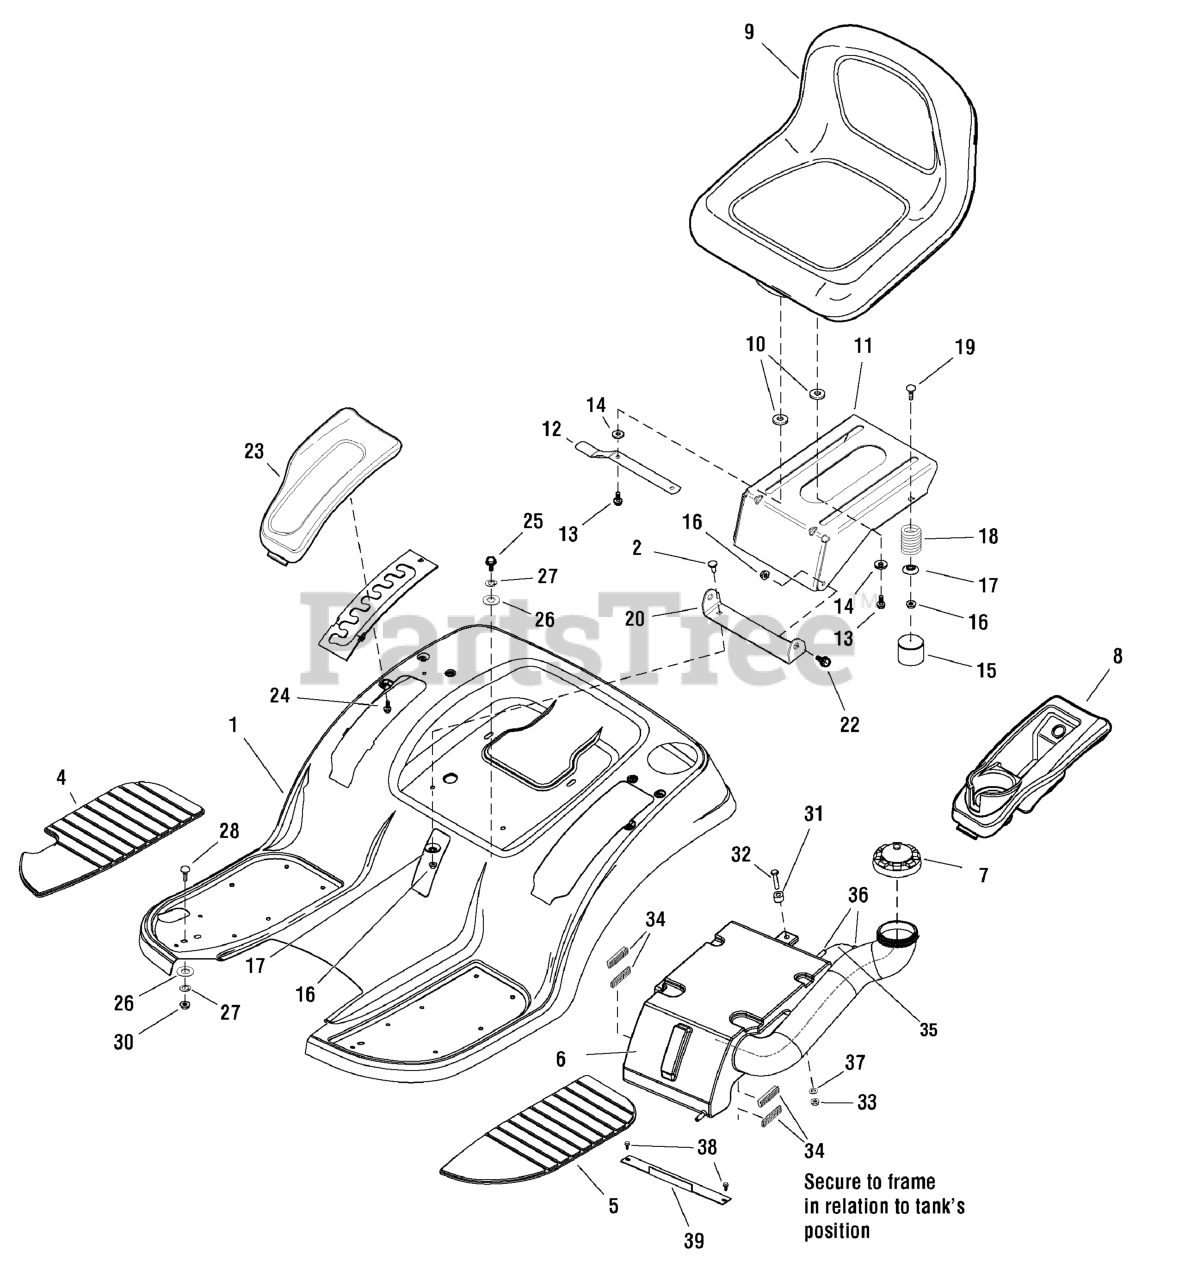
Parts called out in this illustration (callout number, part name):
1	DECK, Seat With Foot Rests
2	BOLT, 5/16-18 X 3/4
4	PAD, Footrest, Right
5	PAD, Footrest, Left
6	FUEL TANK
7	CAP, Fuel
8	POD, Cup Holder, Left
9	SEAT, High Back
11	SUPPORT, Seat
12	LATCH, Seat
13	SCREW, Flange, DOG PT, 5/16-18 x 1.0
14	WASHER, 0.312
15	COVER, Spring
16	NUT, Hex-Flange 5/16-18
17	WASHER, Spring, 5/16 x 1 1/4
18	SPRING, Compression
19	BOLT, RD 5/16-18 x 3/4
20	PIVOT, Seat
22	BOLT, Shoulder, 5/16-18 x 15/32
23	POD, RH Lift
24	SCREW, Hex PLASTT 0.250 x 0.50
25	BOLT, M8 x 16
26	WASHER, 8.4
27	WASHER, 8
28	BOLT, M8 x 20
31	DISTANCE, Lift
32	BOLT, M6 x 30
34	BRAID, Steel Insert
35	HOSE, Air-Escape
37	WASHER, 6.6
38	SCREW, ST 5.5 x 19
39	HOLDER, Tank
